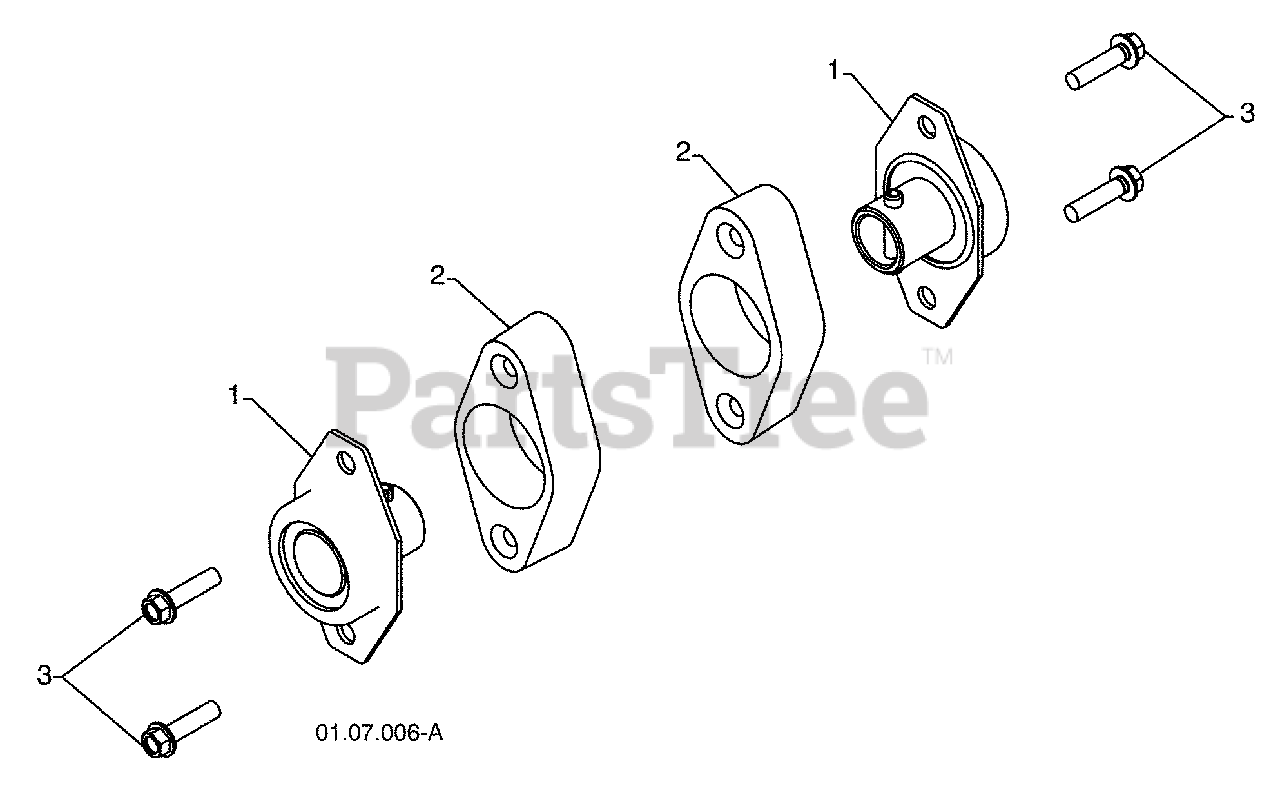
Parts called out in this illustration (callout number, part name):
1	AUGER BALL BEARING
2	PLASTIC RETAINER
3	SCREW 5/16-18 X 1.00
